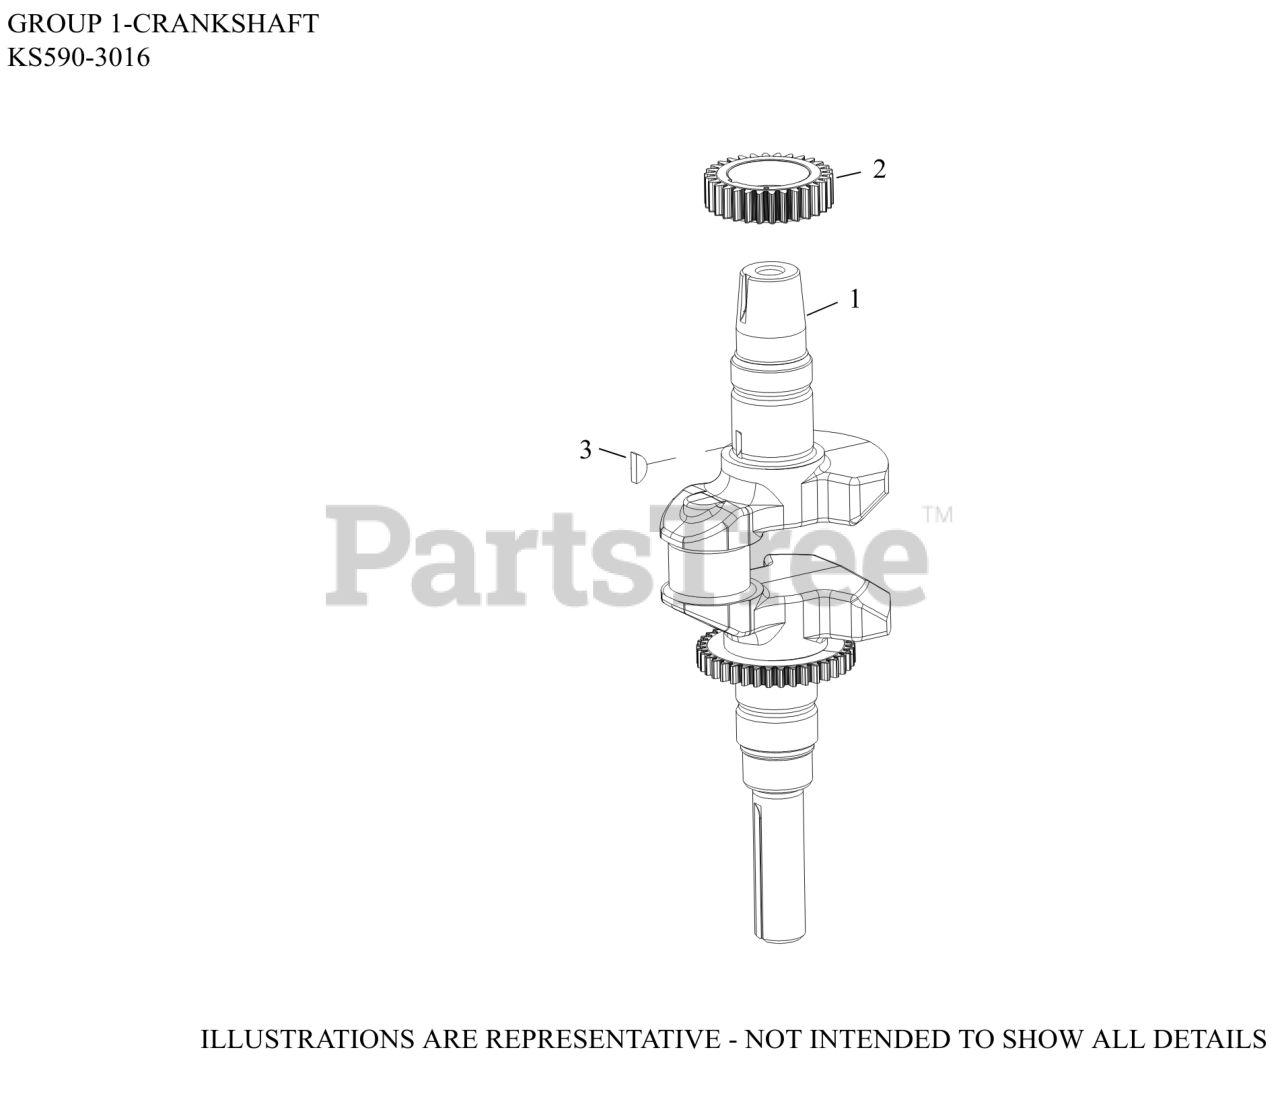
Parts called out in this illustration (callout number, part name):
1	CRANKSHAFT ASSEMBLY
2	GEAR, CRANKSHAFT
3	KEY, 3/16" X 5/8"
